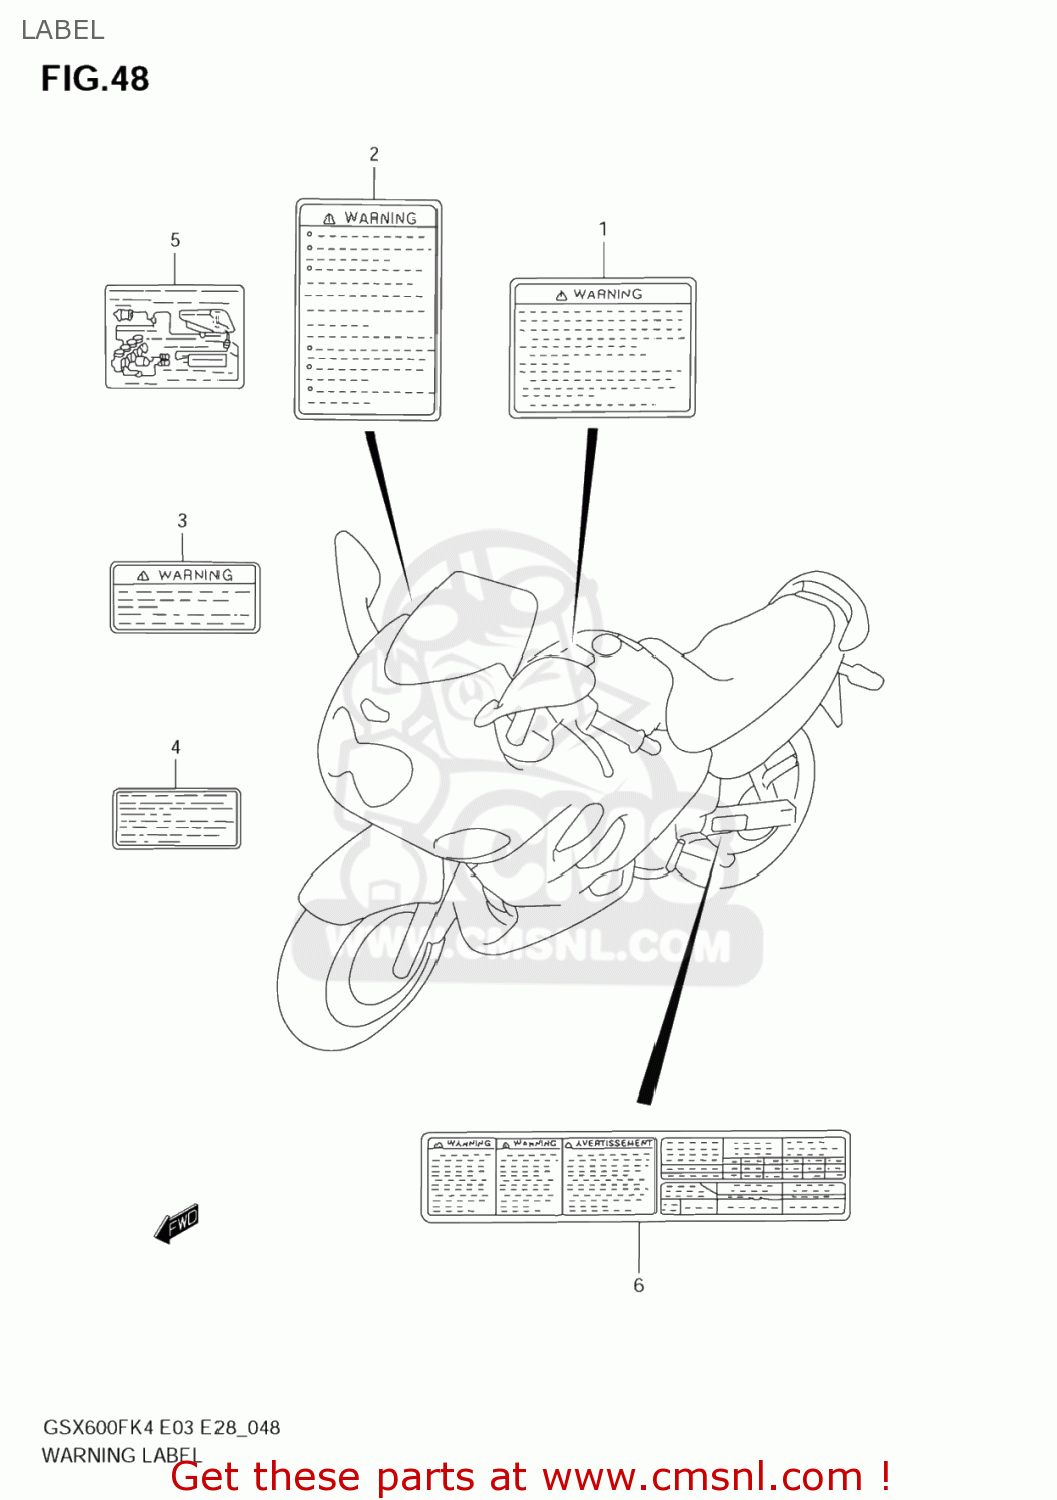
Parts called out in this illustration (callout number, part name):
1	LABEL,GENERAL WARNING
2	LABEL,SCREEN
3	LABEL,WARNING STEERING
4	LABEL,MANUAL NOTICE
5	LABEL,VACUUM HOSE ROUTING
6	LABEL,TIRE INFORMATION
7	MANUAL,OWNER'S
